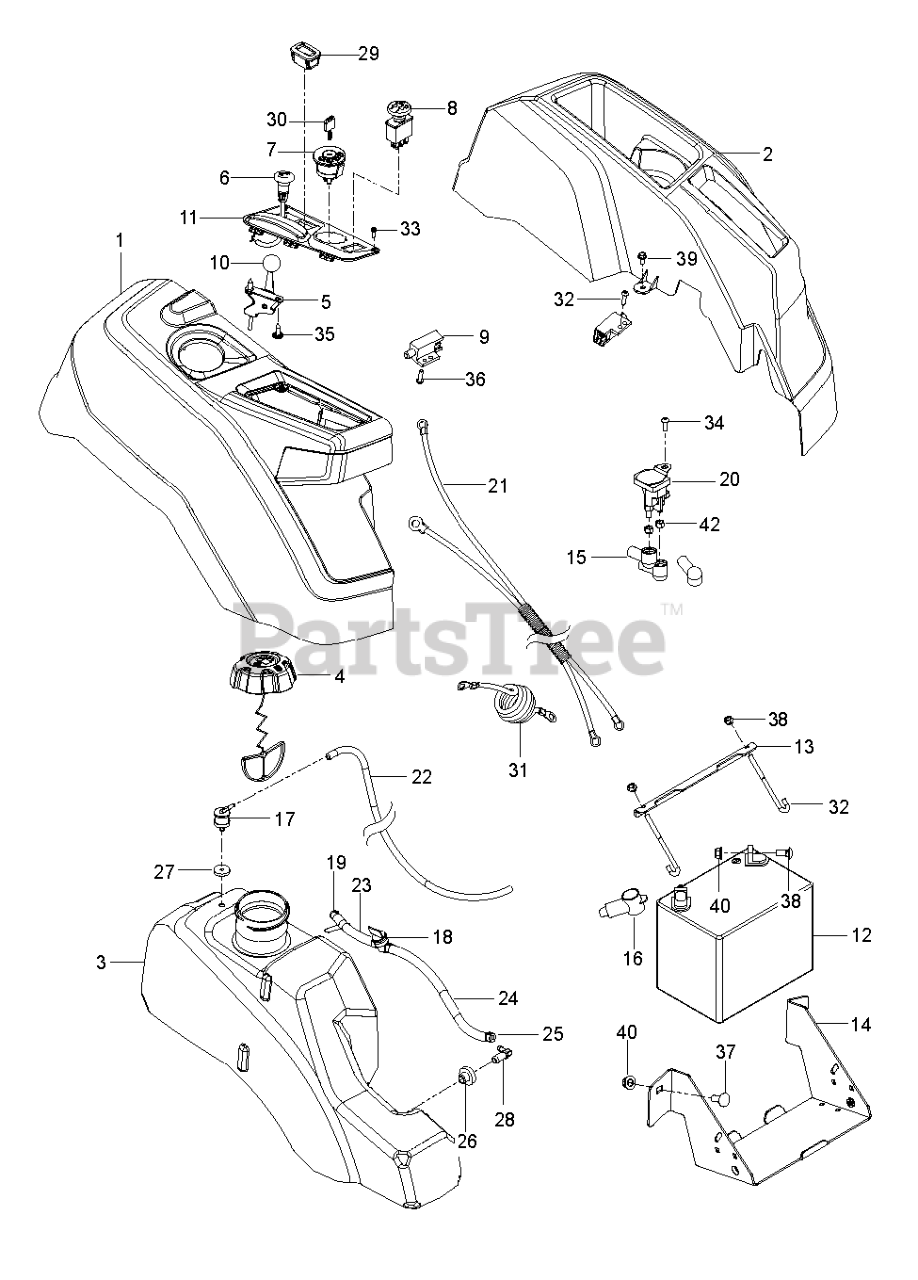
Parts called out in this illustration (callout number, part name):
1	CONSOLE.ASSY.RZ.REFRESH.RH
2	CONSOLE.LH.ASM
3	TANK.ASM3"NECK.NOCAP.NOSHDRZ18
4	FUEL CAP
4	CAP ASSY FUEL 3" GRAY
5	THROTTLE CABLE
6	CHOKE.PUSH-IN.STYLE
7	RP IGNITION SWITCH
8	RP SWITCH.PTO.TERMINAL.STD.RED
9	SWITCH.INTLK.RZ.RFRSH.BUTTON
10	KNOB.ROUND.BALL.BLACK
11	CONTROL.PANEL.RZ.REFRESH.RH
12	BATTERY WET NOT SELLABLE
13	BRACKET.PNT.MOUNT.BATTERY.EDIP
14	BOX.PNT.BATTERY.RZ.EDIP
15	TERMINAL COVER
17	VALVE.FUEL.CHECK
18	FUEL VALVE
19	FUEL.HOSE.SHUT.OFF.ASM.10".18"
20	SOLENOID.STARTER.BRASS.PLUNGER
21	HARNESS.BTTRY.CABLE.RZ.REFRESH
22	HOSE.3/16".VAPOR.LINE.50"LGTH
23	HOSE.1/4".LOW.PERM.FUEL.LN.10"
24	HOSE 1/4" LOW PERMEATION FUEL
25	HOSE CLAMP
26	BUSHING OUTLET T
27	GROMMET.ROV.SENTEC
28	STEM FUEL TANK
29	GUAGE.SRVCMNDR.HRMTR.
30	KEY MLD GEN DELTA
31	CABLE BATTERY POS RZ
32	HOOK.J.BATTERY
33	SCREW 6-19X.437
34	SCR 1/4-20 X 5/8 BTN SKT HD ZD
35	SCREW.PAN.HEAD.#10
36	SCREW.BUTTONHD.10-24X1/2.(2 2)
37	RHSNB 3/8C X 1
38	BOLT 5/16C X 3/4" CARRIAGE
39	SCREW
40	5/16-18 NYLOC FLANGE NUT
42	NUT.1/4-20.HEX.NYLOC.ZD
